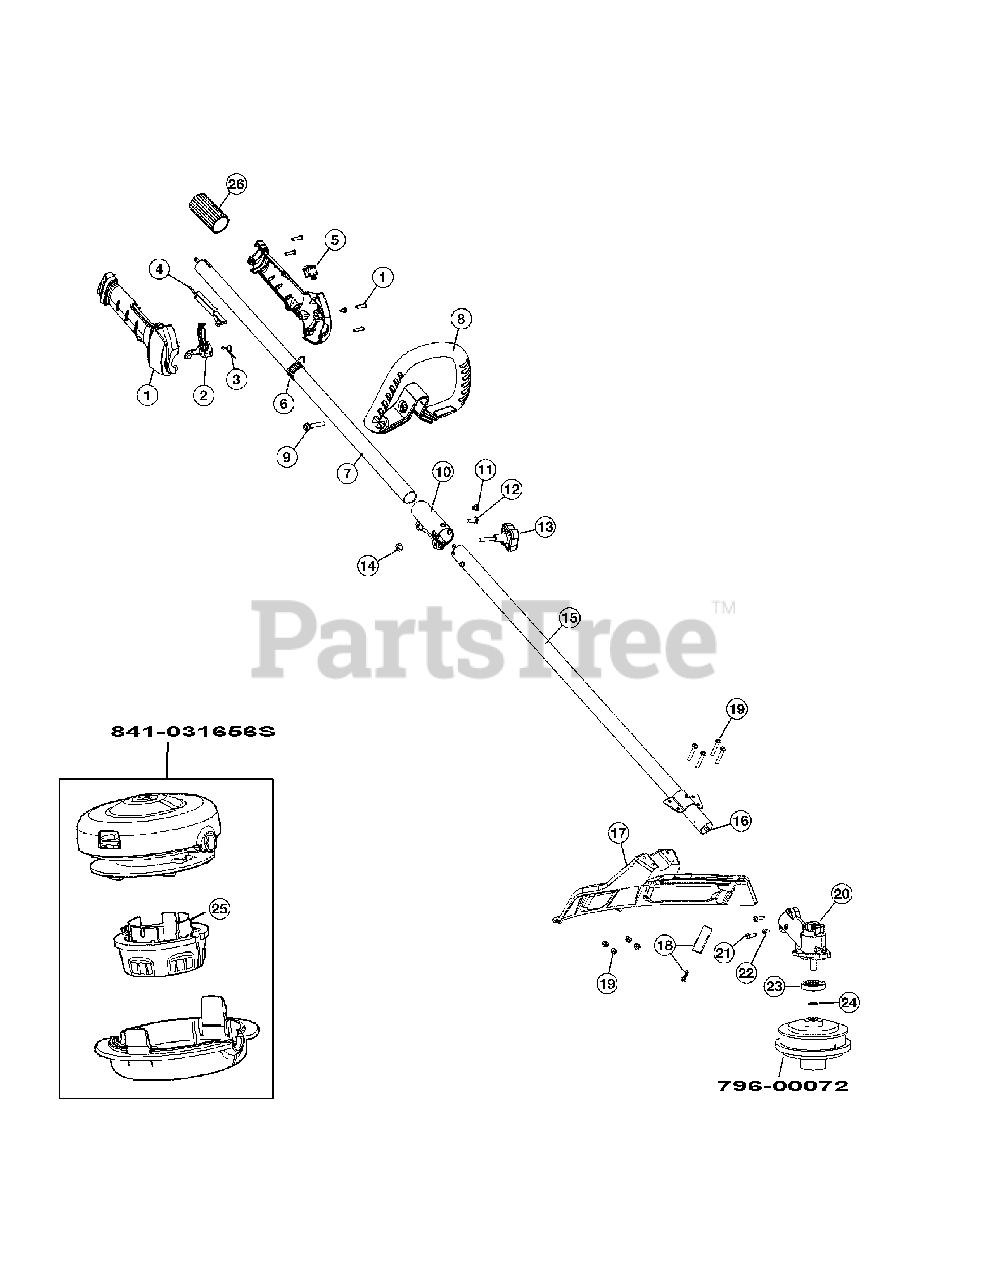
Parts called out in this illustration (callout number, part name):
1	Throttle Housing Assembly
2	Throttle Trigger
4	Throttle Lock-out
6	Shoulder Strap Clip
7	Upper Drive Shaft Housing Assembly
8	D-Handle Assembly
10	Split Boom Coupler
11	Coupler Anti-Rotation Screw
13	Adjustment Knob
14	Knob Retaining Nut
15	Lower Drive Shaft Housing Assembly
16	Lower Flexible Drive Shaft
17	Shield Assembly
18	Blade Assembly
19	Shield Mounting Screw & Nut
21	Gearbox Mounting Hardware
22	Anti-Rotation Screw
23	Blade Driver
26	Grip Spacer
796-00072	Cutting Head Assembly
841-031656S	Cutting Head Assembly
